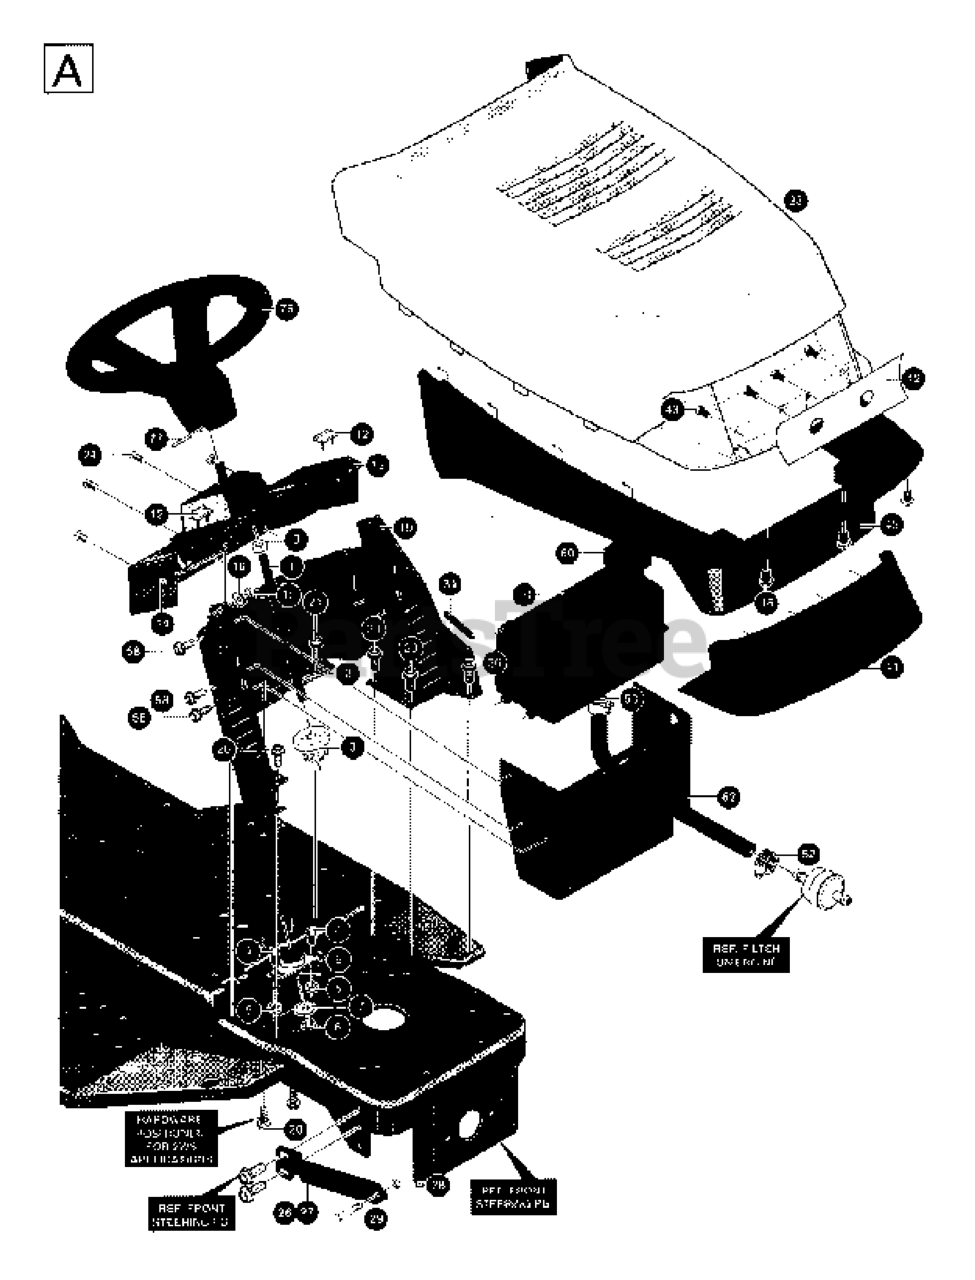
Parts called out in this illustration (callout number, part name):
1	SHAFT
3	GEAR
7	WASHER
8	RETAINING RING
15	NUT
16	WASHER
20	SCREW
21	SCREW
24	SCREW
28	NUT
52	HOSE CLAMP
53	HOSE CLAMP
60	TANK CAP
